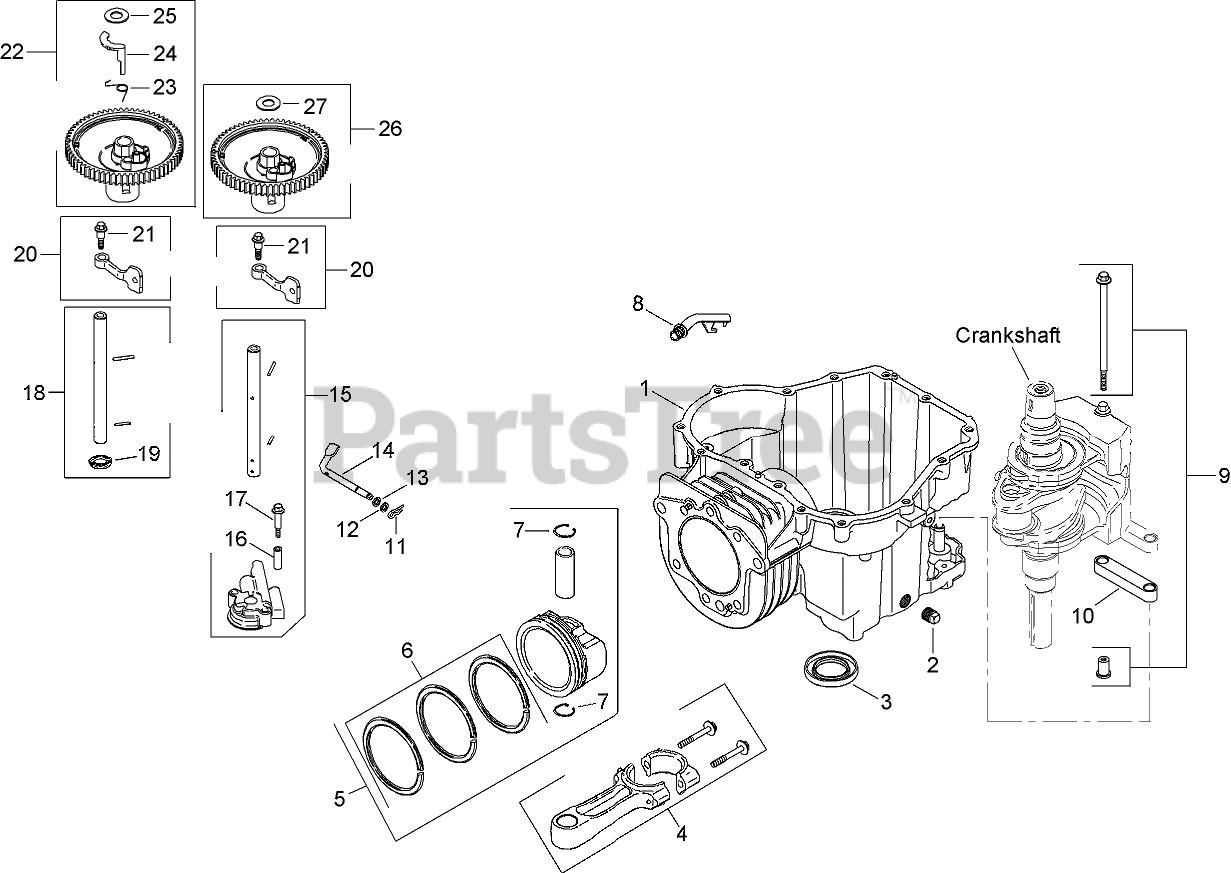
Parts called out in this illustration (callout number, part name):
1	CRANKCASE (SV590/600 SHORT BLOCK)
2	PLUG-PIPE, SQ HD (3/8)
3	Seal-Oil
4	Connecting Rod ASM
5	Piston and Ring Set (94 mm)
6	Ring Set (94 mm)
7	Retainer-Pin, Piston
8	Tube-Back, Drain
9	LOCATING PIN ASM
10	LINKAGE-WEIGHT, BALANCE
11	Clip-Pin, Hitch
12	WASHER-FLAT (6mm)
13	WASHER-FLAT (1/4)
14	Shaft-Cross, Governor
15	Oil Pump ASM
16	Spacer-Screw, Oil Pump
17	Screw-Pump, Oil
18	CAMSHAFT CENTER ASM (EXHAUST)
19	WASHER-THRUST
20	Cam Lever ASM
21	Bolt-Shoulder (M6x1x26)
22	Cam Gear ASM
23	Spring-A C R
24	Weight-A C R
25	Washer-Thrust, A C R
26	Cam Gear ASM
27	Washer-Thrust, A C R
